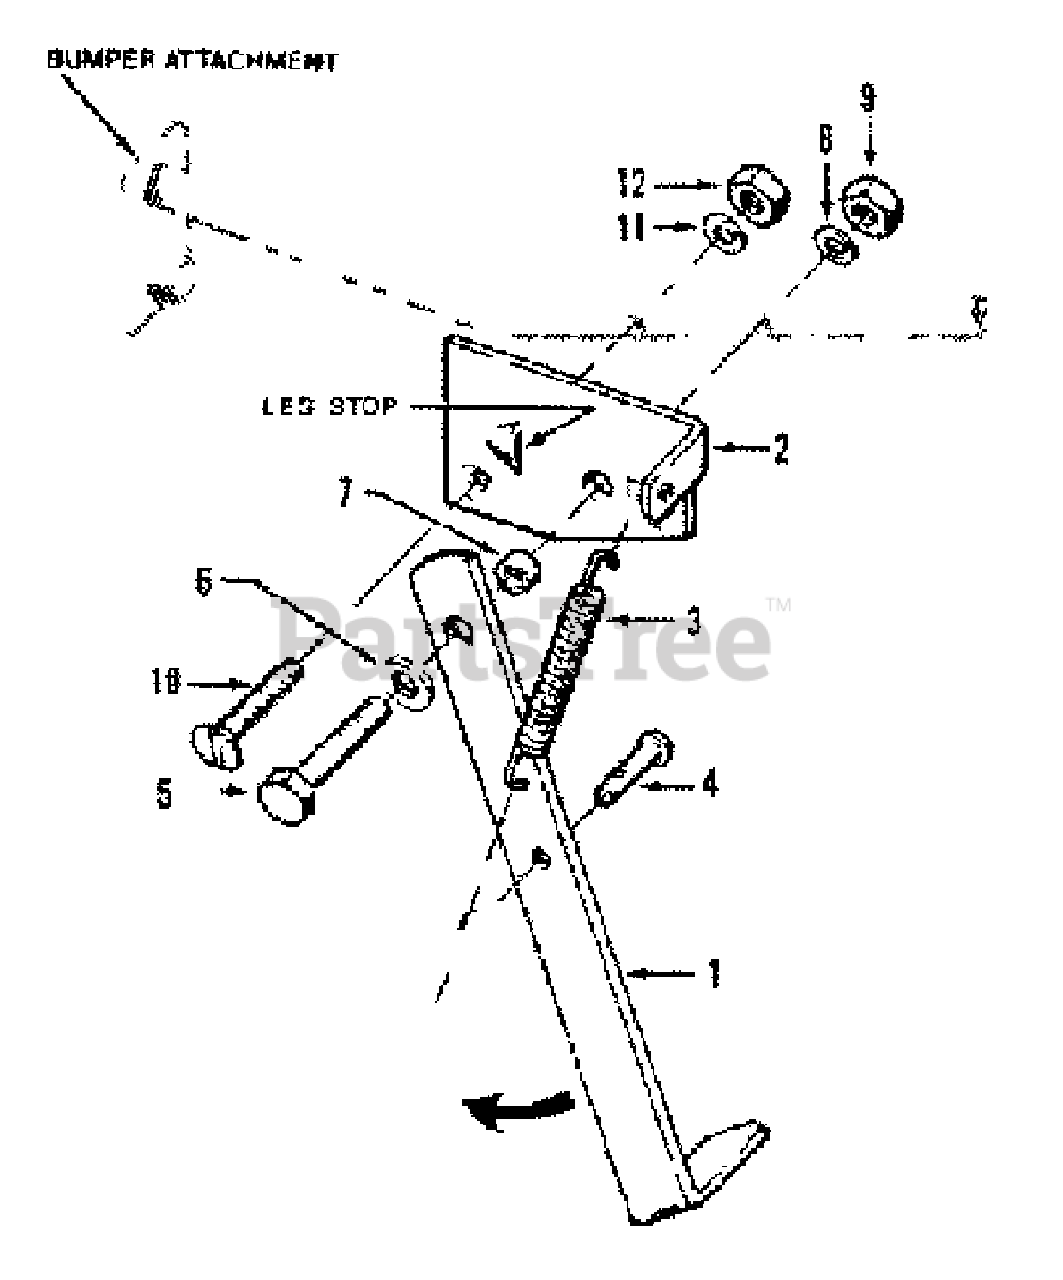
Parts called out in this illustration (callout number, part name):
1	Leg-kickstand
2	Plate-kickstand mounting
3	Spring-kickstand
4	Pin-clevis
5	Bolt-hex hd., 5/16-18 x 2", Grade 5
6	Washer - flat, 5/16", S.A.E.
7	Bushing-.438"/g. (.313" O.D., .275" I.D.)
8	Lockwasher-spring lock, 5/16"
9	Nut-hex, 5/16"-18
10	Screw-flat hd., 1/4"-20 x 1-1/2"
11	Lockwasher-spring lock, 1/4"
12	Nut-hex, 1/4"-20
